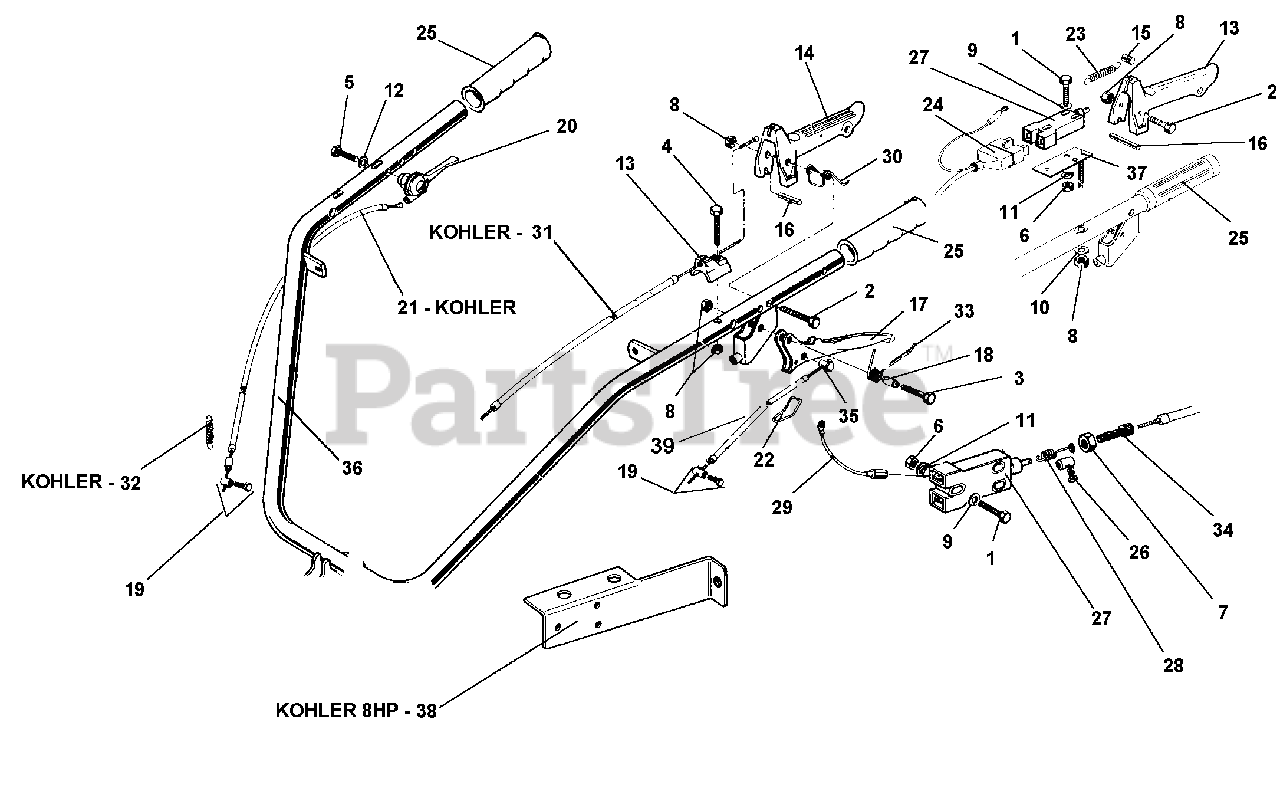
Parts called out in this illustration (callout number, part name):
1	SCREW TE M4 X 25
2	SCREW TE M6 X 45
3	SCREW M6 X 25
4	SCREW M6 X 35
5	SCREW TE M8 X 40
8	NUT, SELF LOCKING M6
9	FLAT WASHER 4.3
10	FLAT WASHER 6.4 X 12.5
11	LOCK WASHER 4.3
12	LOCK WASHER 8.4
13	CABLE STOP OF MOTOR STOP
14	MOTOR STOP LEVER
16	LEVER STOP FOR MOTOR STOP
17	CLUTCH LEVER
18	LEVER SPACER
19	CLAMP, CABLE
20	LEVER, ACCELERATOR
21	THROTTLE CABLE, 725
23	MOTOR STOP SPRING
24	MOTOR STOP CABLE, B&S
26	CABLE CLAMP
27	STOP SWITCH
28	SWITCH SPRING
29	SWITCH CABLES
30	MOTOR STOP LEVER SPRING
31	THROTTLE CABLE, 725 KOHLER
32	SPRING, KOHLER THROTTLE
33	LEVER SPRING
34	ADJUSTING SCREW
37	STOP SWITCH SUPPORT
38	SWITCH SUPPORT, KOHLER
39	CABLE, CLUTCH
